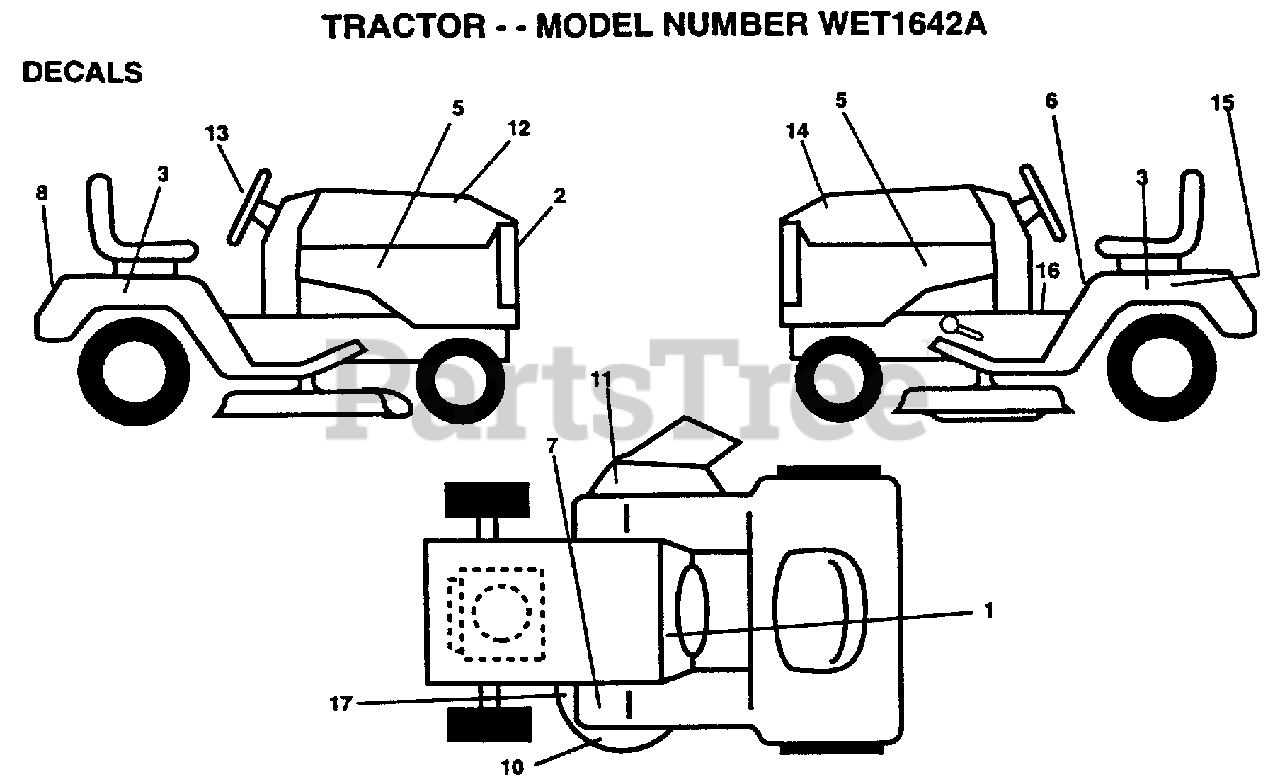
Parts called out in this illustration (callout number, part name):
1	DECAL.DASH.INSTR.
2	DECAL.GRILL
3	DECAL.FEND.QUICKS
5	DECAL.PNL.SD.WEED
6	DECAL CAUTION
7	DECAL T
8	DECAL.FENDER
10	DECAL.MOWER
11	"DECAL, WARNING"
12	DCL.HD.WET1642A
13	DECAL.WHL.STRG.
14	DECAL, HOOD LH
15	DECAL
16	DECAL BRAK PARK
17	DECAL
